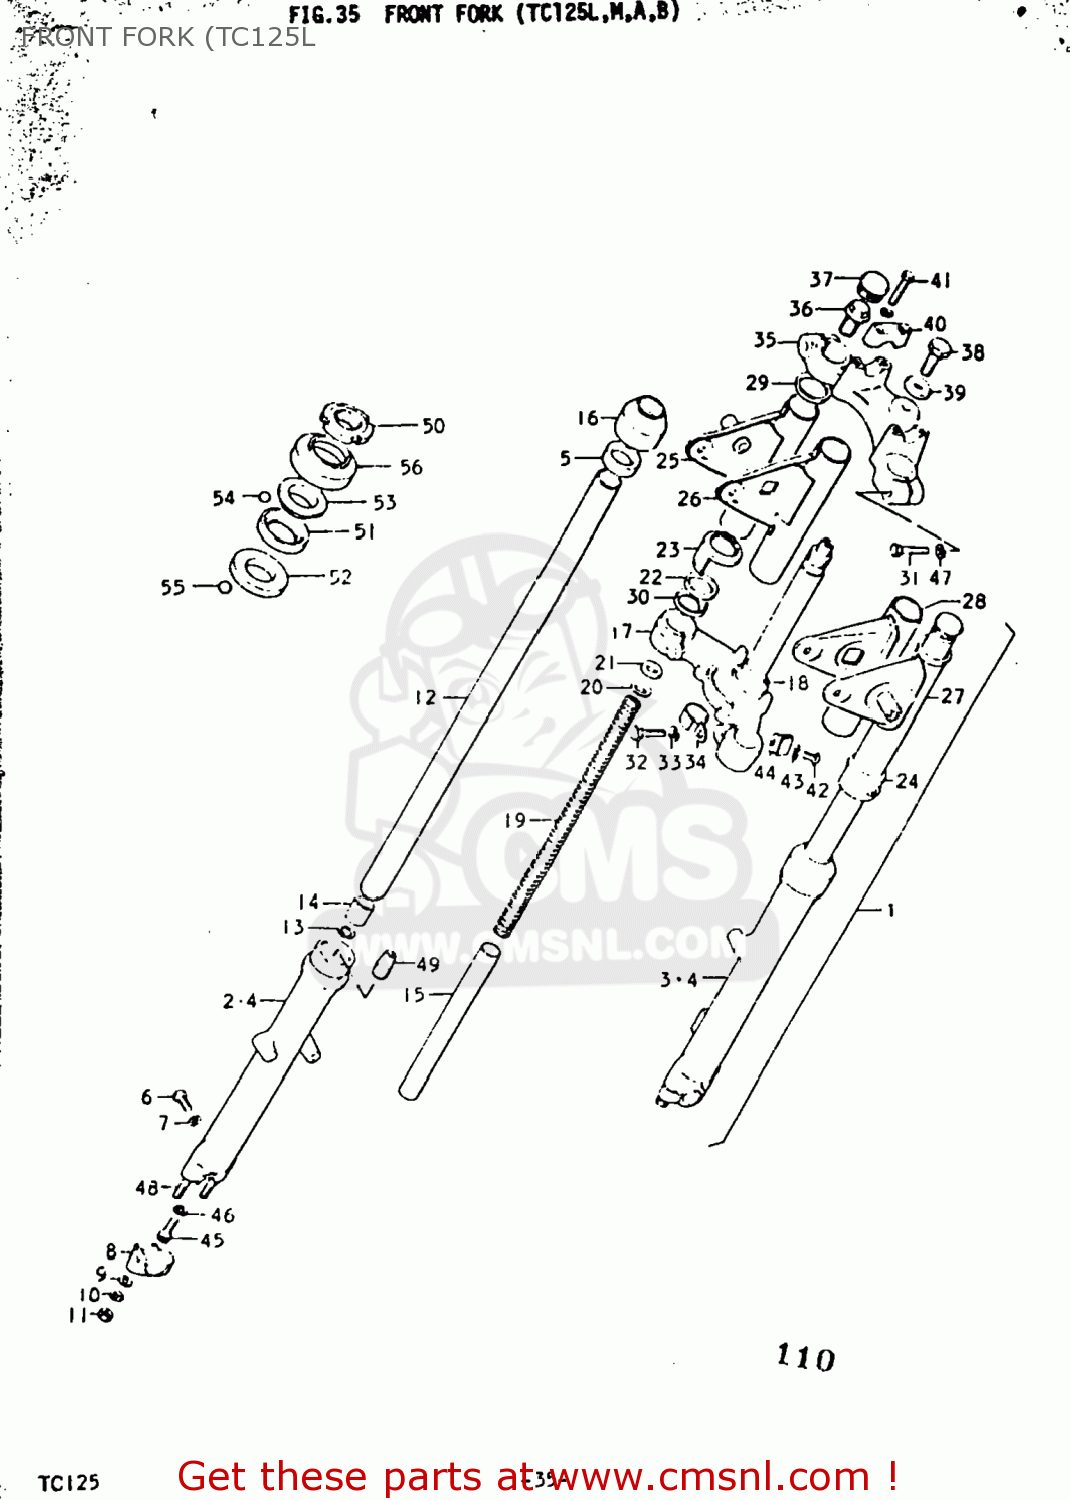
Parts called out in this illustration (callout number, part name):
1	DAMPER SET
2	TUBE,OUTER,RIGHT
3	TUBE,OUTER,LEFT
4	TUBE,OUTER,LEFT
5	SEAL,OIL
6	SCREW
7	GASKET,DRAIN,PLUG (NAS)
8	HOLDER,AXLE
9	WASHER
10	LOCK WASHER
11	NUT (8MM)
12	TUBE,FORK,INNER
13	SNAP RING
14	PISTON
15	CYLINDER,FRONT FORK
16	SEAL,DUST
17	STEM,STEERING
18	RACE,STEERING OUTER LWR
19	SPRING,FRONT FORK
20	GUIDE,SPRING
21	SEAT,SPRING
22	CUSHION,HEADLAMP BRACKET
23	CUSHION,HEADLAMP BRACKET
25	BRACKET,HEADLAMP HOUSING
26	BRACKET,HEADLAMP HOUSING
27	BRACKET,HEADLAMP,LEFT
28	BRACKET,HEADLAMP,LEFT
29	SEAT,HEADLAMP BRACKET
30	GUIDE, COVER
31	BOLT,FORK INNER TUBE F
32	BOLT,FORK INNER TUBE F
33	WASHER,LOCK 12
34	CLIP
35	HEAD,STEERING STEM
36	CAP
37	CAP,FRONT FORK
38	BOLT,FORK INNER TUBE
39	WASHER
40	HOLDER,HANDLEBAR
41	Bolt
42	SCREW
43	LOCK WASHER
44	CLIP
45	BOLT
46	GASKET
47	LOCK WASHER
48	BOLT,STUD
49	PIECE,OIL LOCK
50	NUT,STEERING STEM(25X44X10)
51	RACE,STEERING INNER UPR
52	LACE,STEERING INNER LWR
53	RACE,STEERING OUTER UPR
54	BALL
55	BALL
56	DUST SEAL,STEERING UPR
